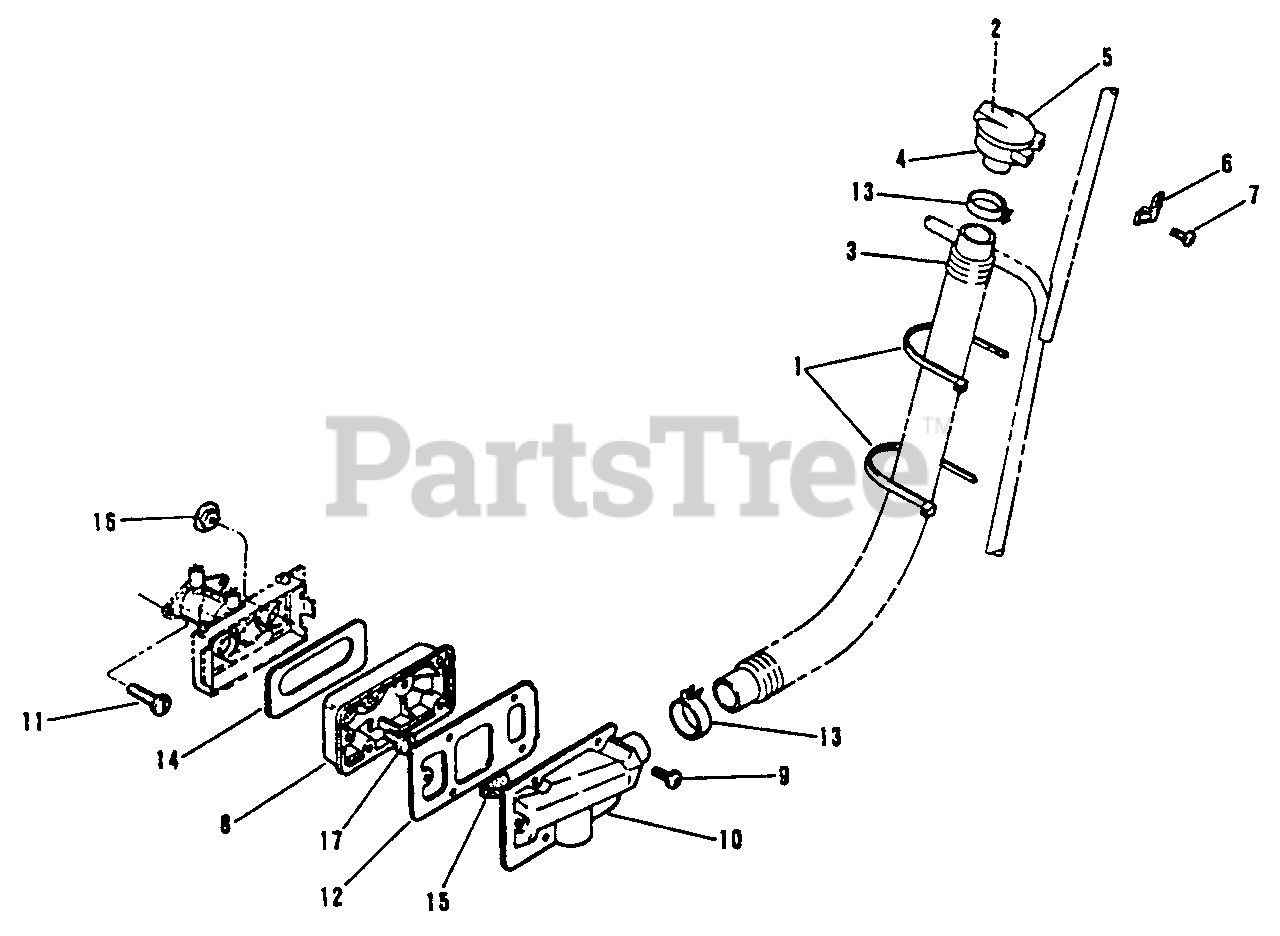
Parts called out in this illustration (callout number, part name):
1	Tie Strap
2	Filter Element
4	Air Filter Chamber
5	Air Filter Cap
8	Chamber Insert
9	Screw
10	Insert Covor
12	Outer Gasket
13	Hose Clamp
14	Inner Gasket
